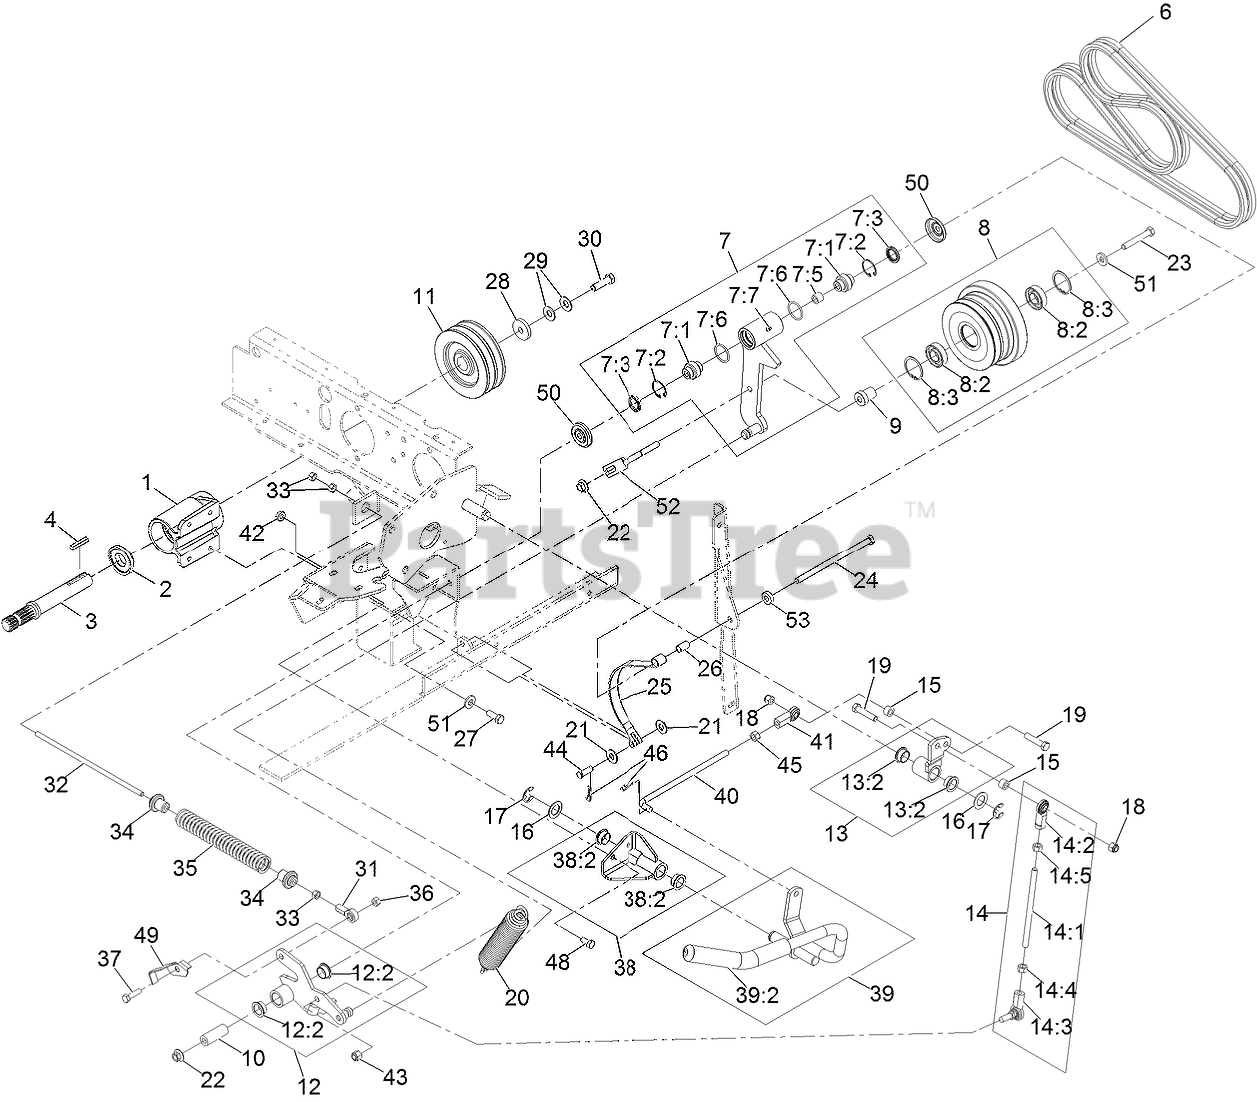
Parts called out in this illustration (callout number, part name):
2	SPACER-GUARD, BOTTOM
3	SHAFT-JACK
4	KEY-SQUARE
6	BELTS-MATCHED PAIR
7	IDLER PIVOT ASM
7:1	BEARING-SPHERICAL
7:2	RING-SNAP
7:3	SEAL-LIP, SINGLE
7:5	BUSHING-LEVER, LIFT
7:7	FITTING-GREASE
8	IDLER SHEAVE ASM
8:2	BEARING-BALL
8:3	RING-RETAINING
9	SPACER-IDLER
10	BUSHING
12	ARM ASM
12:2	BUSHING-BRONZE
13	ARM ASM
13:2	BUSHING-BRONZE
14	CLUTCH LINK ASM
14:1	ROD-LINKAGE
14:2	JOINT-BALL END, LH
14:3	BALLJOINT-RH
14:4	NUT-HEX
14:5	NUT-HEX, LH
18	NUT-LOCK, NI
19	SCREW-HH
20	SPRING-EXTENSION
21	WASHER-FLAT
23	SCREW-HH
24	SCREW-HH
25	BAND-BRAKE
27	SCREW-HH
28	WASHER-CLUTCH
29	WASHER-SPRING
30	SCREW-HH
31	BALLJOINT-RH
32	LINKAGE-ROD, PTO BRAKE
33	NUT-HEX
34	BUSHING-SPRING
35	SPRING-BRAKE
36	NUT-LOCK, NI
37	SCREW-HH
38	PIVOT ASM
38:2	BUSHING-BRONZE
39	PTO HANDLE ASM
39:2	GRIP-LEVER, CONTROL
40	LINK-HANDLE
41	JOINT-BALL, END
43	NUT-LOCK
44	PIN-CLEVIS
45	NUT-HEX
46	PIN-COTTER
48	SCREW-HH
49	SWITCH-FLAG
50	GUARD-TOP
51	WASHER-BELLEVILLE
52	GUIDE-BELT
53	SPACER
